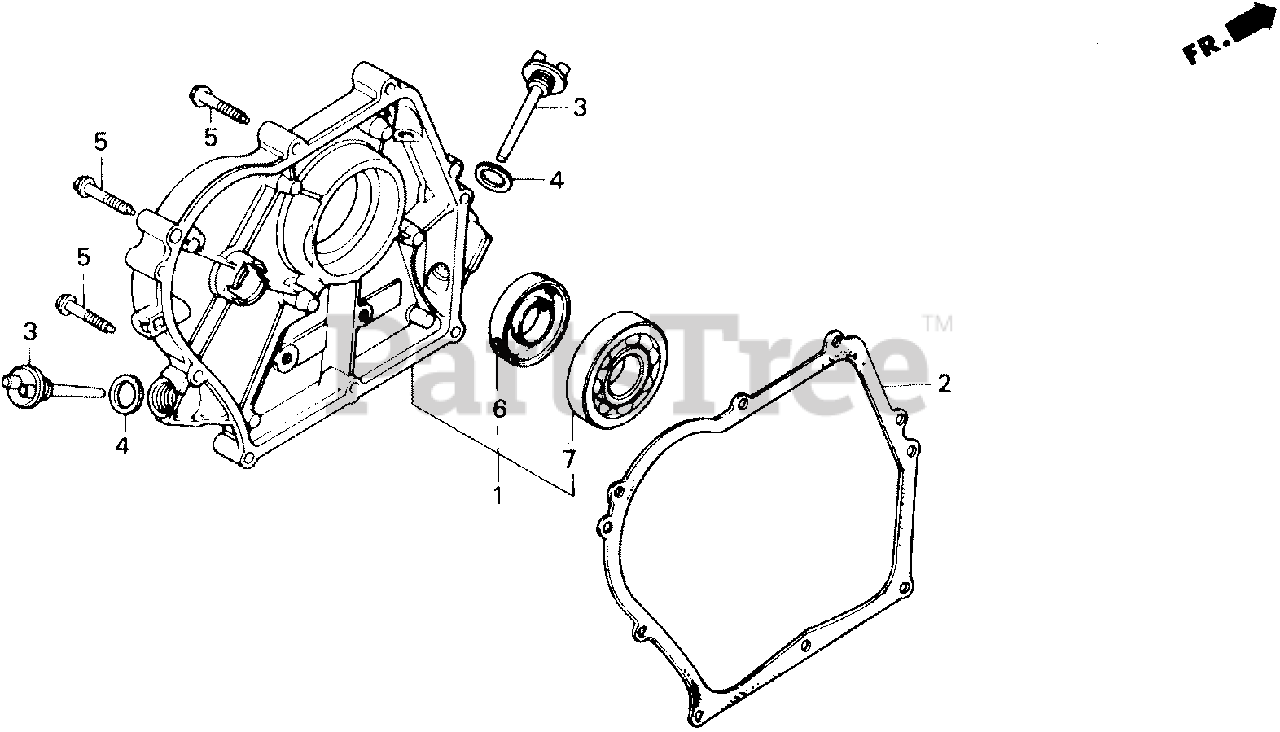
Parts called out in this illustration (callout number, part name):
1	COVER ASSY., CRANKCASE
2	GASKET, CASE COVER
3	CAP, OIL (YELLOW)
4	GASKET, OIL FILLER CAP
5	BOLT, FLANGE (6X32)
6	OIL SEAL (25X41X6)
7	BEARING, RADIAL BALL (6205)
